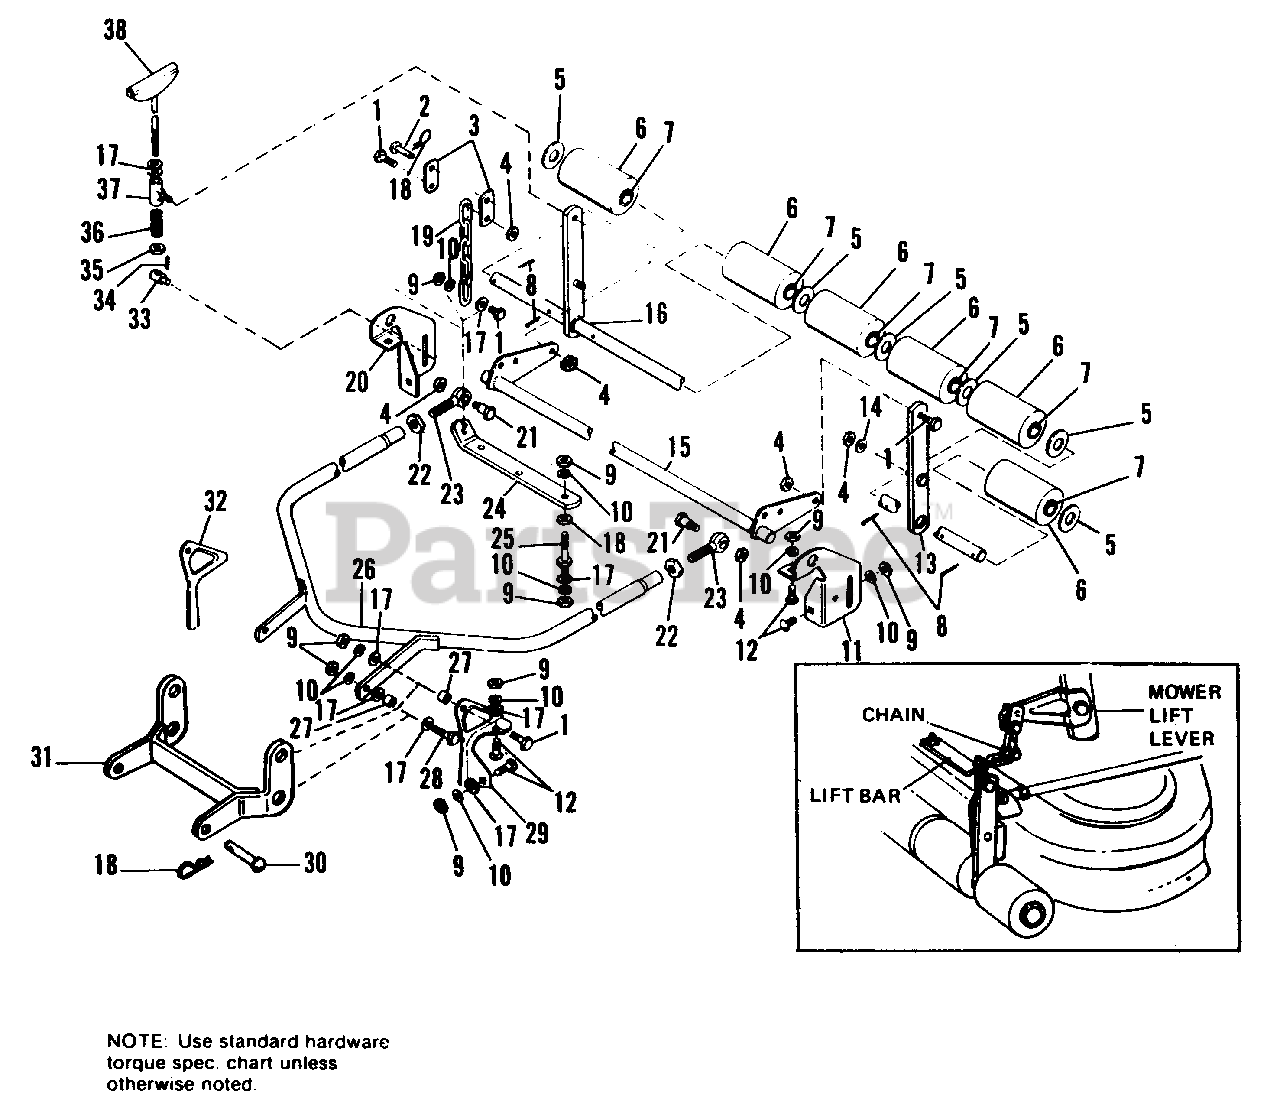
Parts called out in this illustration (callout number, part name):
1	CAPSCREW, Hex Hd., 3/8-16 x 1
3	LINK, Mower Lift
4	LOCKNUT, Hex, 3/8-16
6	ROLLER ASSY., W/Bushings
8	PIN, Cotter, 3/16 x 1
9	NUT, Hex, Full, 3/8-16
10	LOCKWASHER, 3/8
11	BRACKET, Rear, L.H.
12	BOLT, Carriage, 3/8-16 x 3/4
13	BAR ASSY., Roller
14	WASHER, Plain, 5/16
15	LEVER ASSY., Rear
16	ROLLER BAR & SHAFT ASSY.
17	WASHER, Plain, 3/8
18	CLIP, Hair Pin
19	CHAIN
20	BRACKET, Rear, R.H.
21	BOLT, Shoulder
22	LOCKNUT, Hex, Jam, 1/2-20
24	BAR, Lift
26	BAIL ASSY.
28	CAPSCREW, Hex Hd., 3/8-16 x 1-1/4
29	BRACKET, Front, L.H.
31	ARM ASSY., Rocker
32	BRACKET, Front, R.H.
34	PIN, Cotter, 3/32 x 3/4
35	LOCKNUT, Hex, Jam, 3/8-16
37	SOCKET ASSY., Crank
38	SCREW ASSY., Adjusting
